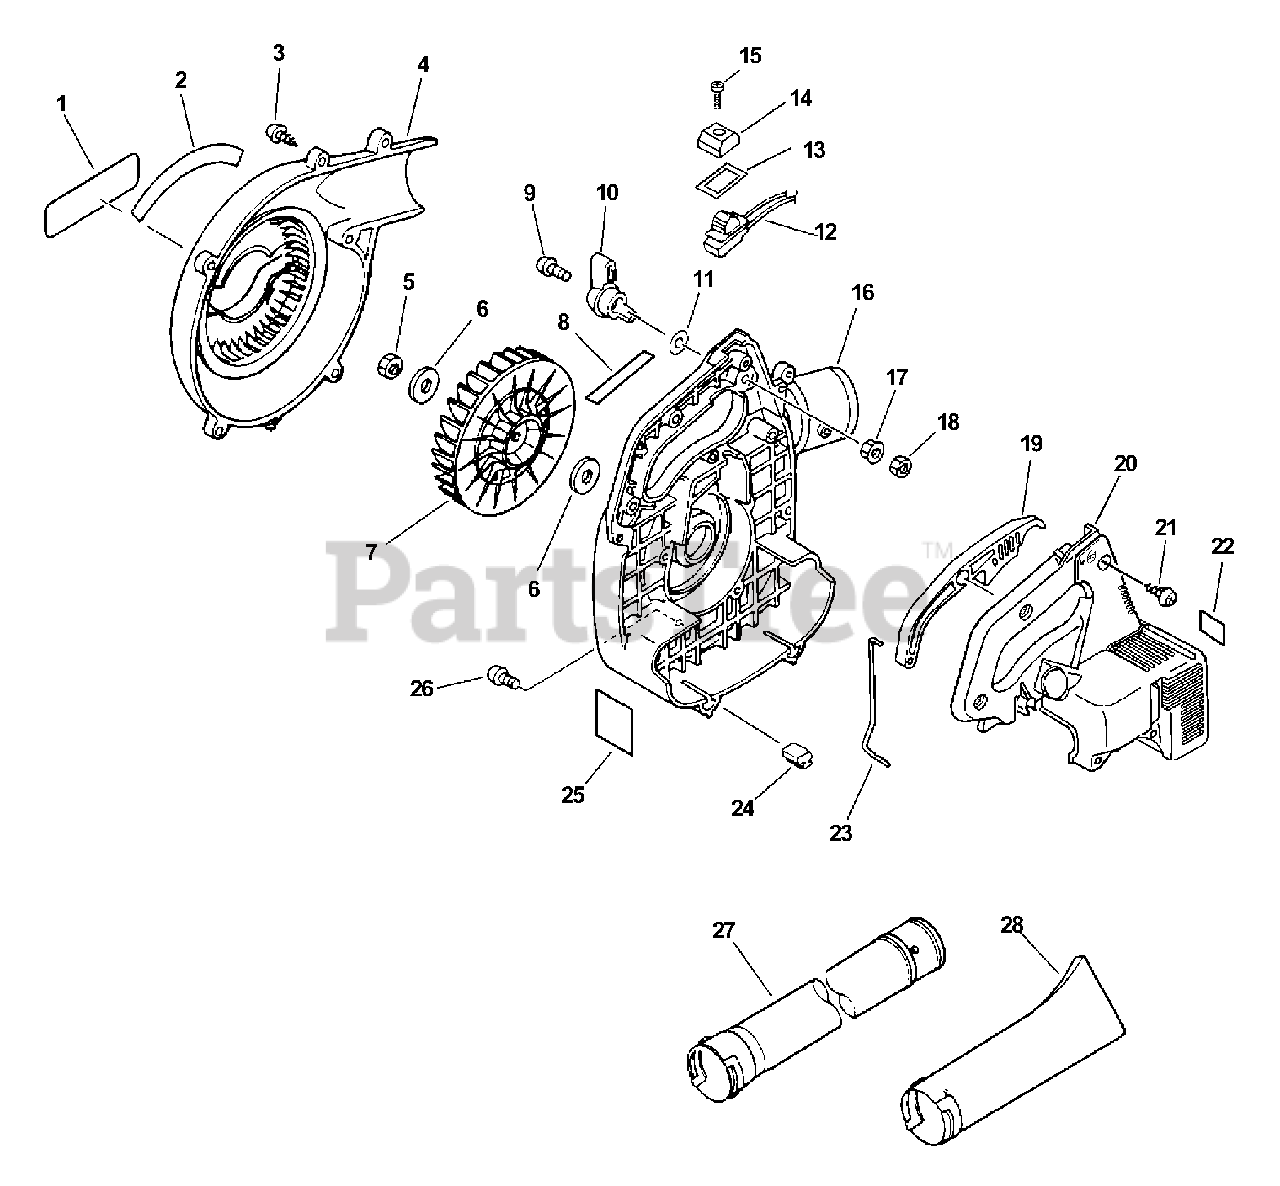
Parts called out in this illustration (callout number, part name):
1	LABEL - ECHO
2	LABEL, MODEL
3	SCREW, TAPPING 5×20
4	COVER, FAN
8	LABEL - NOISE
9	SCREW 5×25
10	CONTROL, THROTTLE
11	WASHER 5.5×12×0.8
12	IGNITION SWITCH ASSY
13	LABEL, SWITCH
14	KNOB, SWITCH - ORANGE
15	SCREW 3×10
16	COVER, FAN - RIGHT
17	NUT, FLANGE M5
19	CONTROL, THROTTLE
20	COVER, ENGINE
21	SCREW, TAPPING 5×20
22	LABEL, CAUTION - HOT
23	ROD, THROTTLE
25	LABEL - CAUTION
26	SCREW 4×22
27	TUBE, BLOWER - STRAIGHT
28	TUBE, BLOWER - NOZZLE
